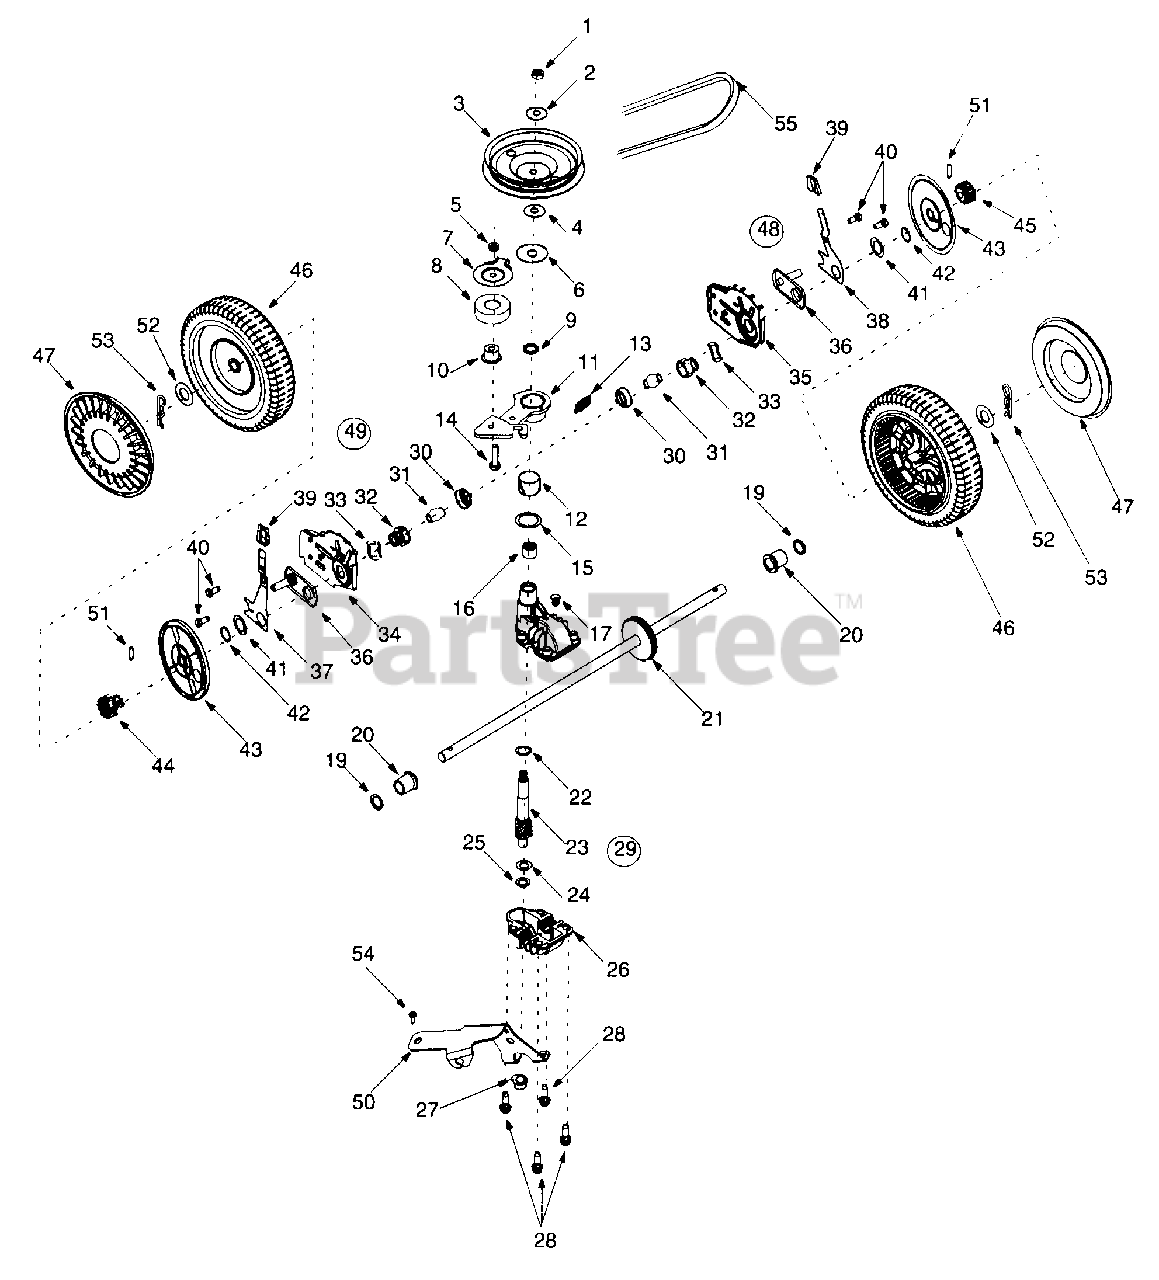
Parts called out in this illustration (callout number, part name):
1	Hex Jam Nut 5/16-24
2	Bell Washer .325 x .930 x .045
3	Pulley, 3.82 x .313 x .68
4	Bell Washer .325 x .930 x .045
5	Lock Nut 1/4-28
6	Flat Washer .442 x 1.38 x .060
7	Belt Keeper
8	Ball Bearing
9	Oil Seal
10	Flange Spacer
11	Idler Bracket Assembly
12	Bearing Sleeve
13	Flat Washer .504 x .700 x.030
14	Hex Cap Screw 1/4-28 x 1.00
15	Flat Washer .865 x 1.145 x .030
16	Needle Bearing .438 x .625 x .500
17	Plug 1/4 x .437
19	Oil Seal .500 x .687 x .094
20	Flange Bearing
21	Output Shaft
22	Flat Washer .504 x .700 x .030
23	Pinion Shaft 10T
24	Thrust Washer .375 x .70 x .030
25	Thrust Washer .388 x.625 x.062
26	Lower Housing
27	Flange Bearing .378 x .531 x .370
28	Hex Screw w/Washer 1/4-20 x .750
29	Transmission Assembly
30	Bearing Retainer
31	Bearing Sleeve.50 I.D.
32	Bearing Support
33	Wave Washer 1.5 x 1.0 x .029
37	RH Front Lever
38	LH Front Lever
39	Knob
40	Hex Cap Screw 3/8-16 x .75
41	Washer DD 1.5" O.D.
42	Snap Ring 1.0 dia.
43	Wheel Dust Cap
44	Gear 14T RH FWD
45	Gear 14T LH FWD
46	Wheel, 8x2 x 1.75
47	Hubcap: Gray
48	RH Height Adj. Complete
49	LH Height Adj. Complete
50	Cable Idler Bracket
51	Dowel Pin
52	Flat Washer 1/2 x 1.00 x .063
53	Cotter Pin .08 x 1.42
54	Screw
55	Belt
